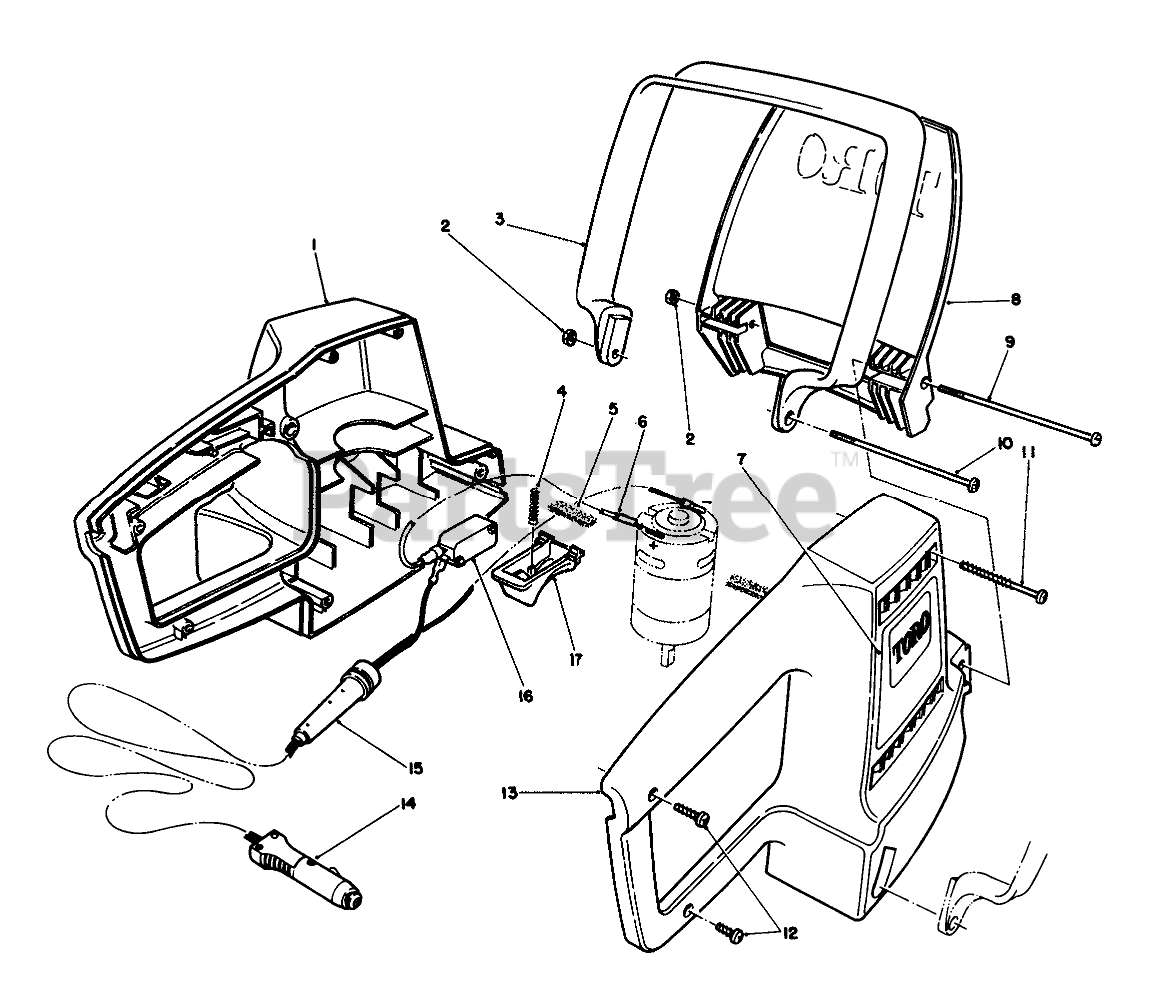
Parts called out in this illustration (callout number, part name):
1	Housing-Handle, L.H.
2	NUT-HJ
3	ASSIST HANDLE
4	SPRING-TRIGGER
5	WIPER
6	WIRE ASSEMBLY
7	DECAL-HEDGE, RT
8	SHIELD
9	SCREW-PPH
10	SCREW-PPH
11	SCREW - #8 X 2.0
12	SCREW-PPH
13	Housing-Handle, R.H.
14	CORD-HEDGE
15	Relief-Strain
16	SWITCH
17	TRIGGER
